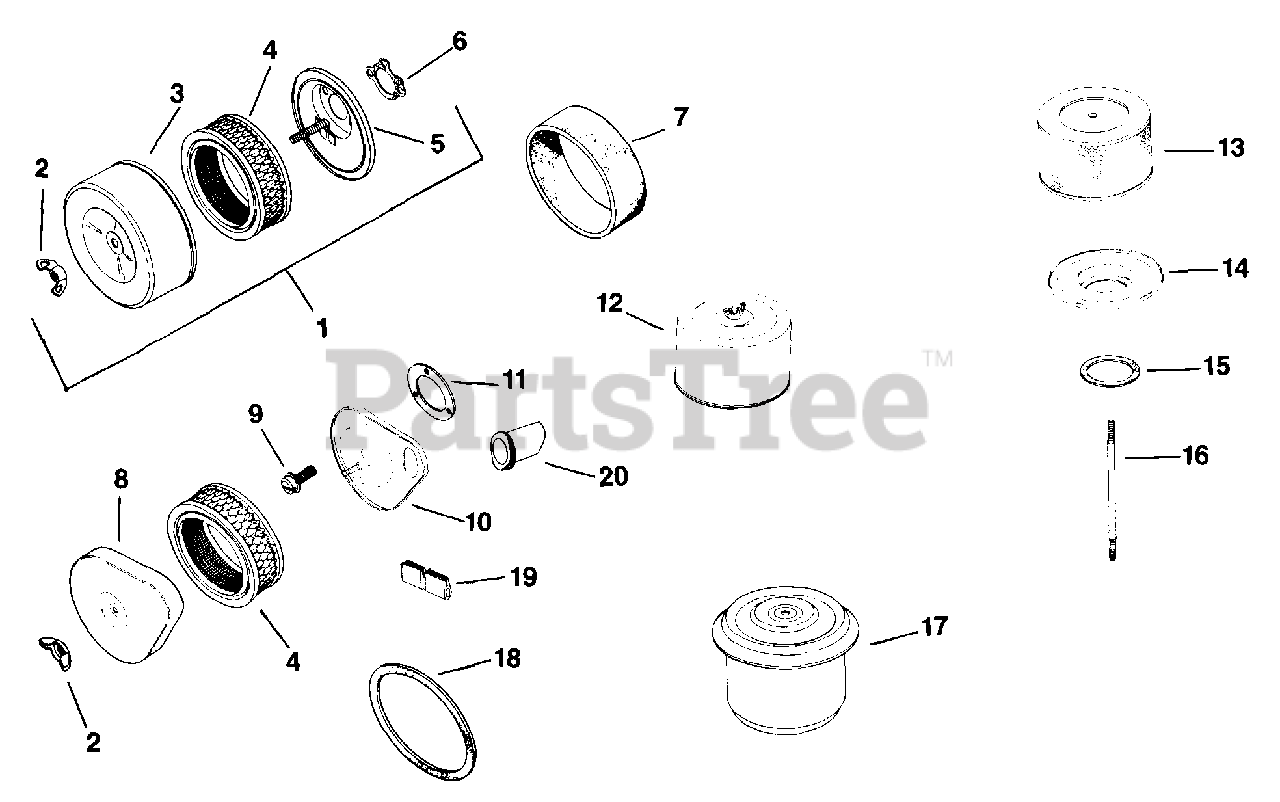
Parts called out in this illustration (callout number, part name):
2	NUT, WING 1/4-20 USE 25 100 15-S
7	PRE-CLEANER USE 237421-S
7	PRE-CLEANER
17	CLEANER
